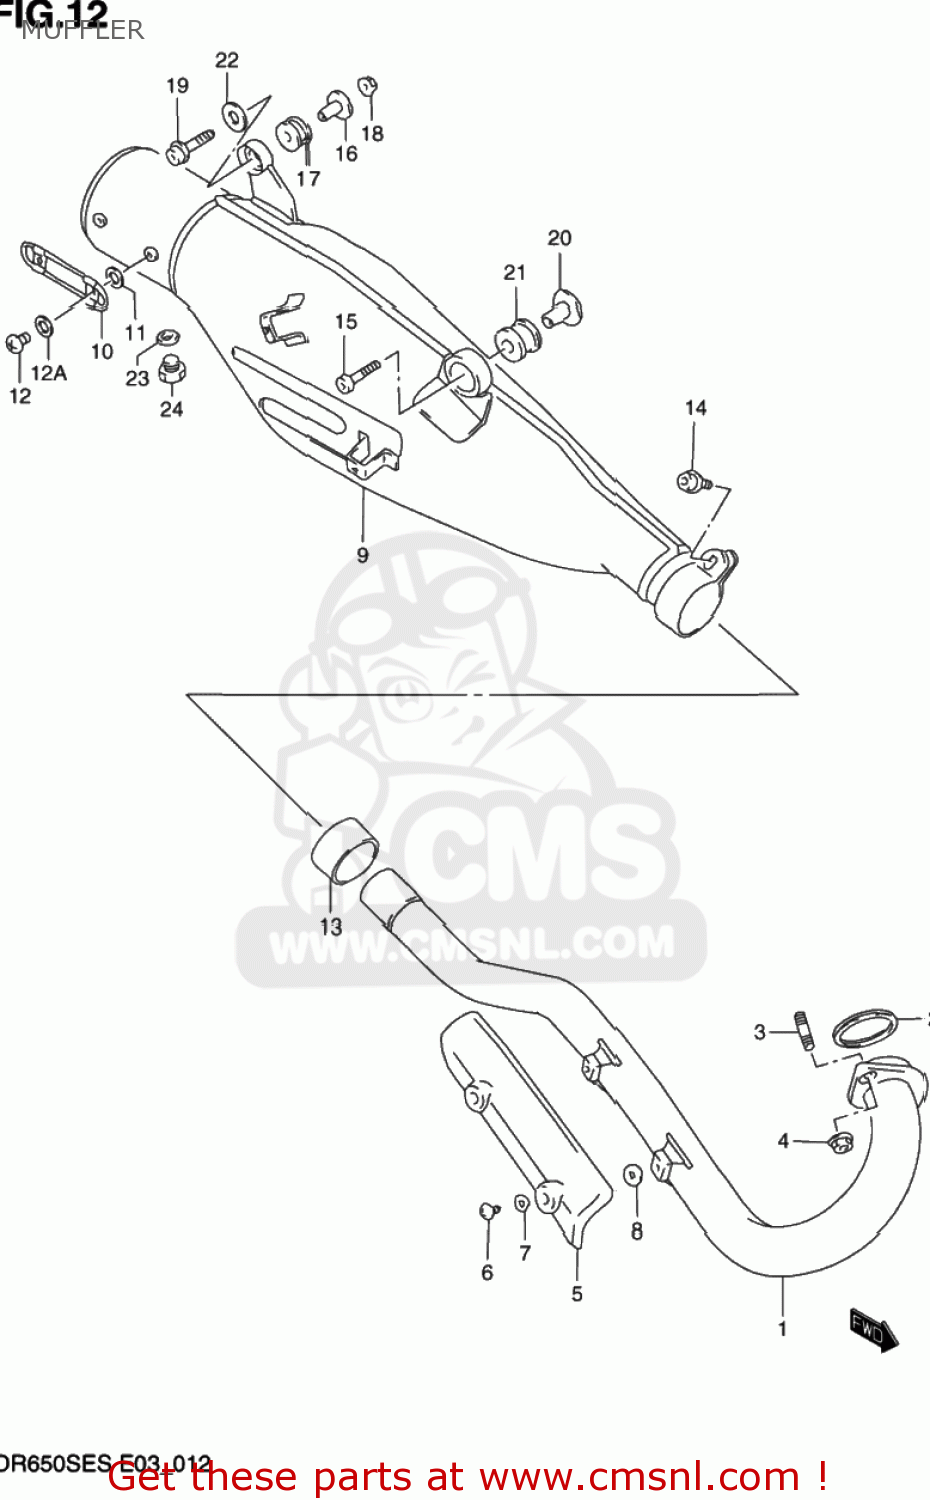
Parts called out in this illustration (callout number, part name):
1	PIPE,EXHAUST
2	GASKET,EXHAUST PIPE (NAS)
3	BOLT,STUD(8X20)
4	NUT
5	COVER,EXHAUST PIPE
6	SCREW(6X10)
7	WASHER(6.5X13X1.0)
8	GASKET(6X16X1.4) (NAS)
9	BODY,MUFFLER
10	COVER,MUFFLER
11	GASKET(5.8X13X1.8) (NAS)
12	SCREW(6X10)
12A	WASHER
13	CONNECTOR,MUFFLER
14	BOLT
15	BOLT(8X40)
16	SPACER(8.6X12X17.5)
17	CUSHION
18	NUT
19	BOLT
20	SPACER(8.6X12X24.2)
21	CUSHION
22	WASHER (8.5X20X1.6)
23	GASKET(12.1X16.2X3.7) (NAS)
24	PLUG(12X9)
